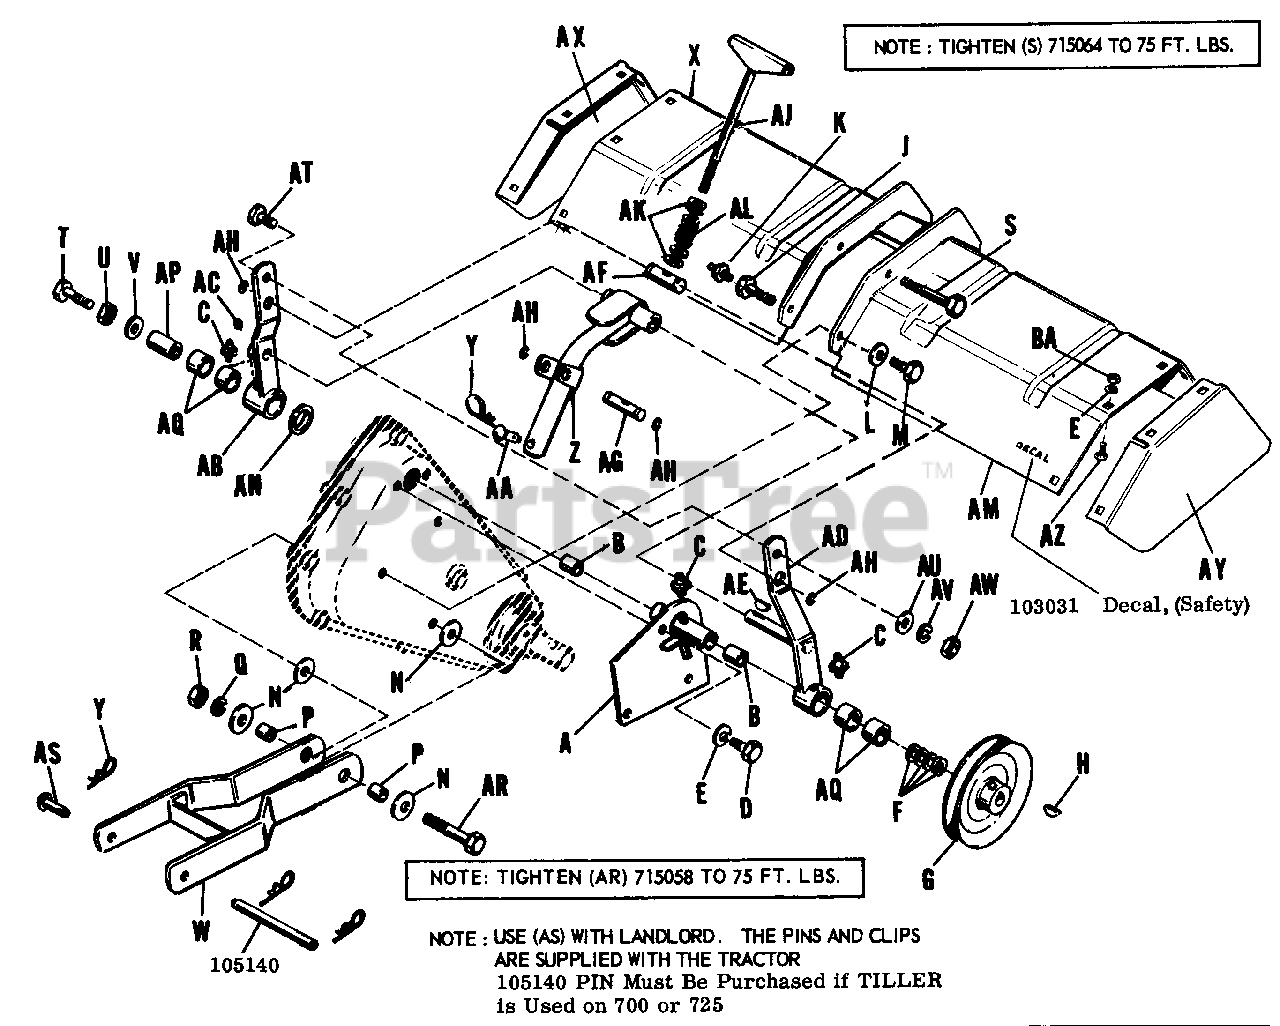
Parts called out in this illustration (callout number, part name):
A	Support Assembly Brg. Hsg.
B	Bearing, Needle
C	Fitting, Grease
D	Capscrew, Hex, 5/16"-18 NC x 3/4" lg.
E	Washer, Lock 5/16"
G	Pulley, Drive
H	Key, Woodruff
K	Fitting, Grease
L	Washer, Plain, 7/16"
M	Capscrew, Hex, 1/2"-20 NF x 1-3/4" lg.
Q	Washer, Lock 7/16"
R	Nut, Hex, Full 7/16"-14 NC
S	Capscrew 7/16"-14 NC x 4" lg.
T	Capscrew 3/8"-24 NF x 2-1/2" lg.
U	Nut, Hex, Jam-3/8"-24 NF
V	Washer, Plain, 3/8"
W	Frame Assembly
Y	Clip, Spring
Z	Bar, Assembly, Lift
AA	Pin
AB	Lever Assembly, R.H., Belt Tension
AC	Screw, Set, Cup Pr., Socket Hd. 5/16"-18 NC x 2/16" lg.
AD	Lever Assembly, L.H. Belt Tension
AE	Key Woodruff #6
AF	Pivot, Upper
AG	Pivot, Lower
AH	Ring, Retaining
AJ	Screw Assembly, Adjusting
AK	Washer Plain 3/8"
AM	Deflector Assembly
AN	Washer Thrust
AR	Capscrew Hex, 7/16"-14 NC x 4-1/2" lg.
AT	Capscrew, Hex, 3/8"-16 x 1" lg.
AU	Washer, Plain 3/8"
AV	Washer, Lock 3/8"
AW	Nut, Hex, Full, 3/8"-16
AX	End Plate RH
AY	lEnd IPlate LH
AZ	Bolt Carriage 5/16"-18 x l/2" lg.
BA	Nut Hex. Full 5/16"-18
